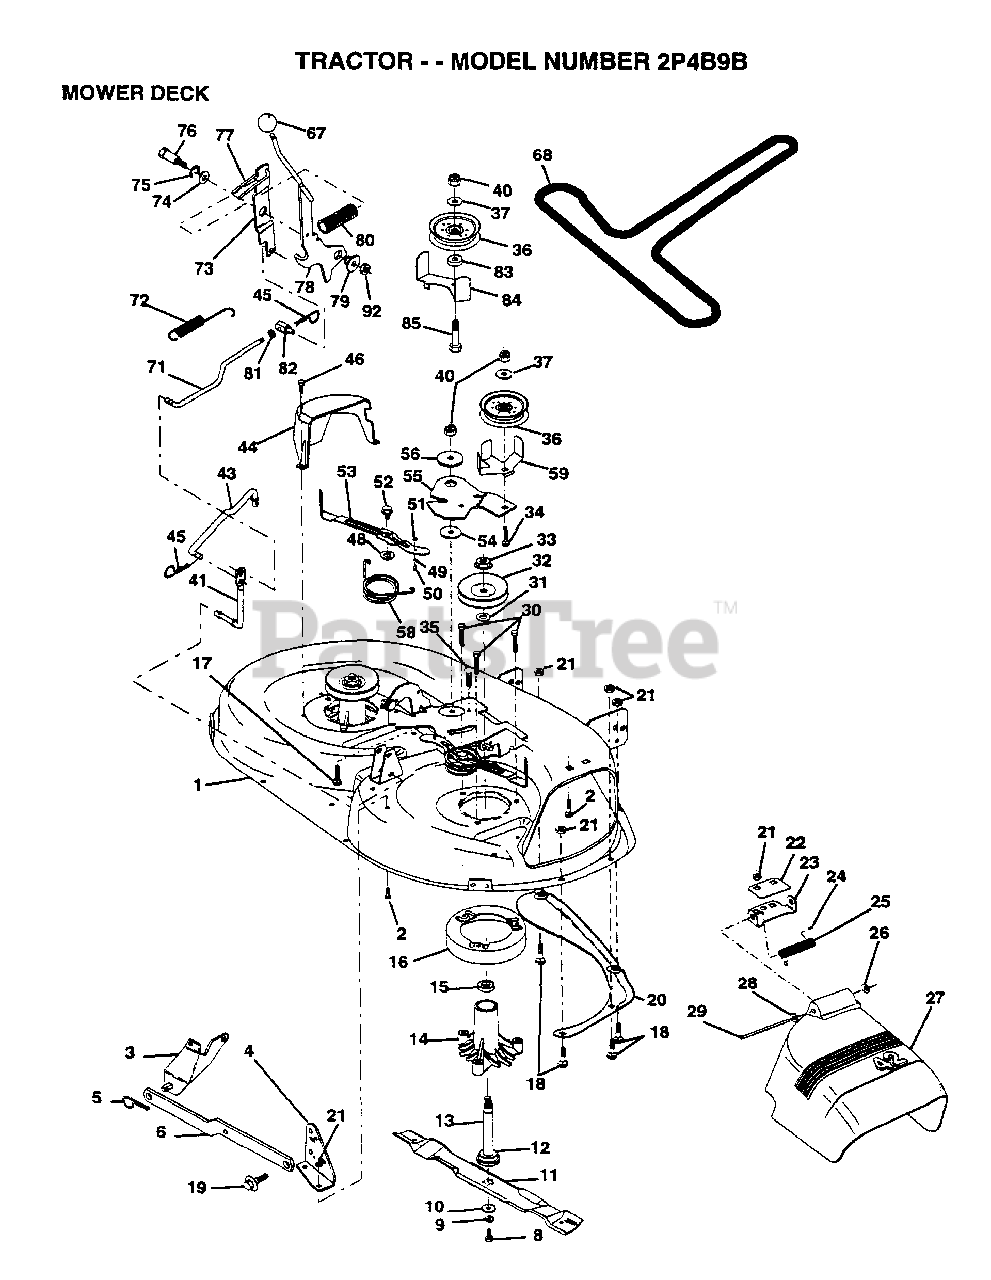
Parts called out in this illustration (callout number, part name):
1	MOWER DECK, ASM. 42"
2	BOLT
3	BRKT ASM SWAY BAR
4	BRKT DECK SW BAR
8	BLADE BOLT
10	WASHER.HARD.BLADE
11	"BLADE.42"" HIPERF"
12	BEARING.BALL
14	HSG ASM MANDREL
15	BEARING
16	STRIPPER RND MWR
17	BOLT RDHD 3/8-16
18	BOLT
19	BOLT SHD 5/16-18
22	STIFFENER BRKT
23	DEFLECTOR BRKT
24	CAP-SLEEVE LT
25	SPRING TORSION
26	NUT PUSH M
27	DEFLECTOR.SHIELD
28	WASHER
29	HINGE ROD
31	WASHER
34	BOLT
35	XMAS TREE FASTNER
36	FLAT IDLER PULLEY
37	WASHER
41	PIVOT ROD
43	ROD CLUTCH W/NIBS
44	GUARD MAND LH BLK
45	RETAINER M
46	SCREW.1/4-20X5/8
48	HARD SMALL WASHER
50	SHOULDER BOLT
51	LOCKNUT
52	BOLT.SHLD.5/16-18
53	BRAKE PAD ARM ASM
54	HARDENED WASHER
56	SPACER RETAINER
58	SPRING TORSN BRAK
59	GUARD IDLER TUV
67	KNOB T(3/8 HOLE)
68	BELT.V.T-PATH
71	ROD CLUTCH 38/42
72	RETURN SPRING
73	CLUTCH ARM SECOND
74	WASHER
75	RING
76	SHOULDER BOLT
77	SPRING KEEPER
79	BUSHING
81	NUT
82	TRUNION ADJ
83	WASHER
85	BOLT
92	NUT
